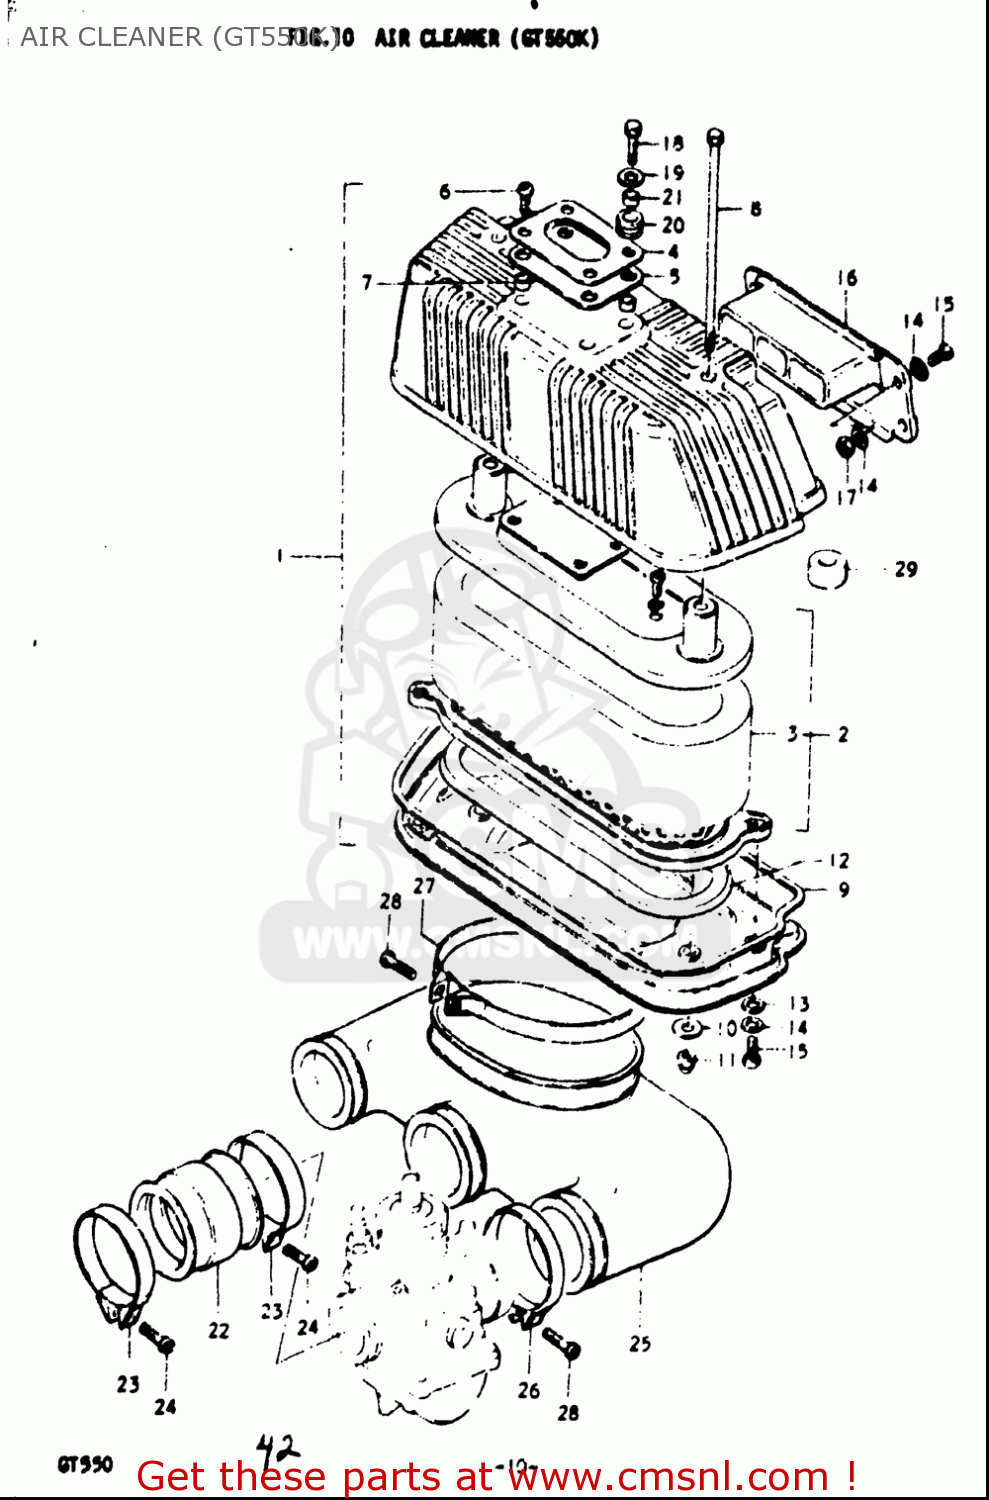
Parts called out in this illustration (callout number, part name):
3	FILTER
6	SCREW
11	NUT
14	WASHER
15	SCREW
17	NUT
18	BOLT
19	WASHER(6.5X20X1.2)
20	CUSHION
21	SPACER,6.5X9X7
22	PIPE,INTAKE
23	CLAMP
24	SCREW
26	CLAMP
27	CLAMP
28	SCREW
